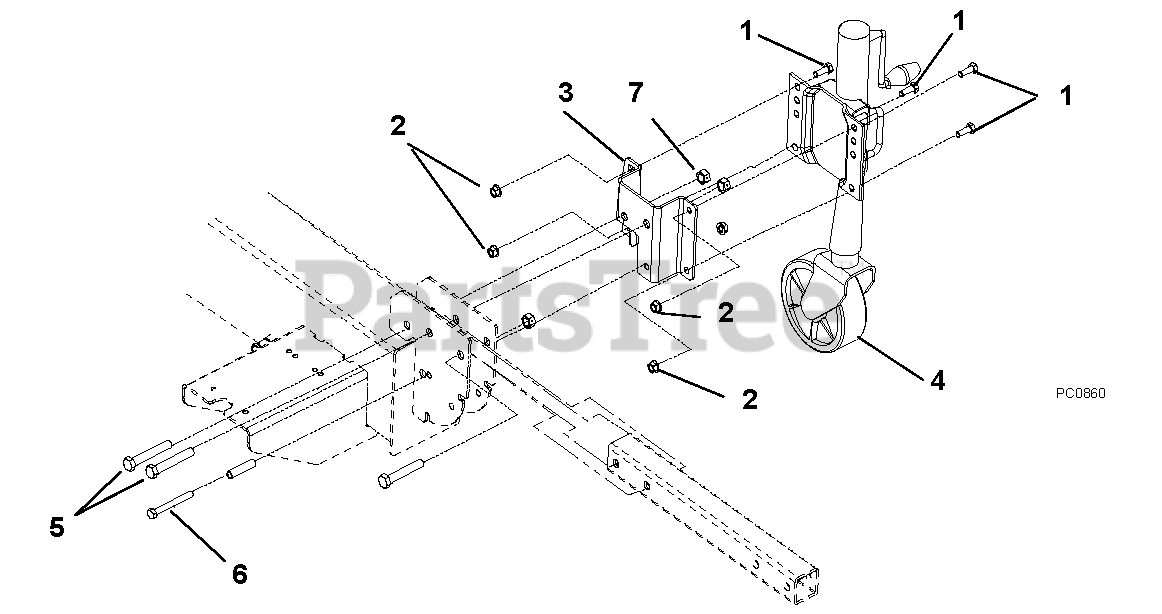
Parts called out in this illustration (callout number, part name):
1	@BLT-HEX .38-16X1.00 GR5 YWZC
2	@NUT-LK-TOP-FLG .38-16 YWZC
3	BRACKET, MOUNTING
4	STAND, JACK-W/WHEEL
5	@BLT-HEX .50-13X3.25 GR5 YWZC
6	@BLT-HEX .38-16X3.25 GR5 YWZC
7	@NUT-LK-CTR .50-13 YWZC
